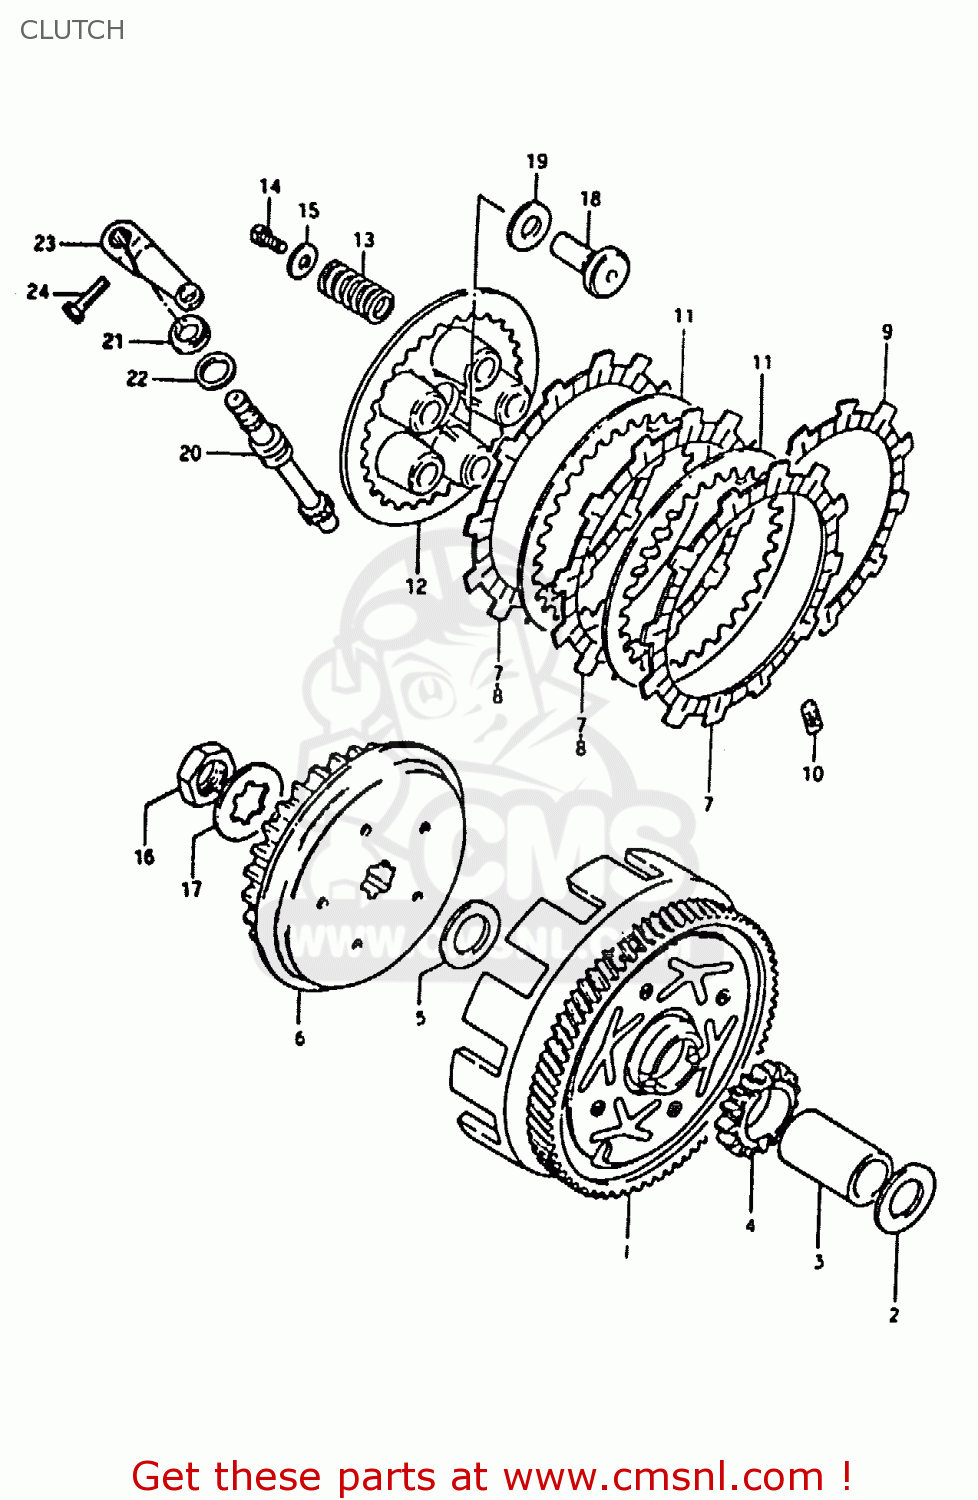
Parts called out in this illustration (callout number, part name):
1	GEAR ASSEMBLY,PRIMARY DRIVE
2	WASHER,THRUST
3	SPACER
4	GEAR,KICK STARTER DRIVE
5	WASHER
6	HUB,CLUTCH SLEEVE
7	PLATE,CLUTCH DRIVE
8	PLATE,CLUTCH DRIVE
9	PLATE,CLUTCH DRIVE (NAS)
10	DAMPER
11	PLATE,CLUTCH DRIVEN (NAS)
12	DISC,CLUTCH PRESSURE
13	SPRING
14	BOLT(5X16)
15	WASHER (5.5X16X1.2)
16	NUT
17	WASHER,LOCK
18	RACK,CLUTCH RELEASE
19	BEARING(10X22X2.8)
20	PINION,CLUTCH RELEASE
21	OIL SEAL
22	WASHER (12X17X1)
23	ARM,CLUTCH RELEASE
24	BOLT, UPPER
